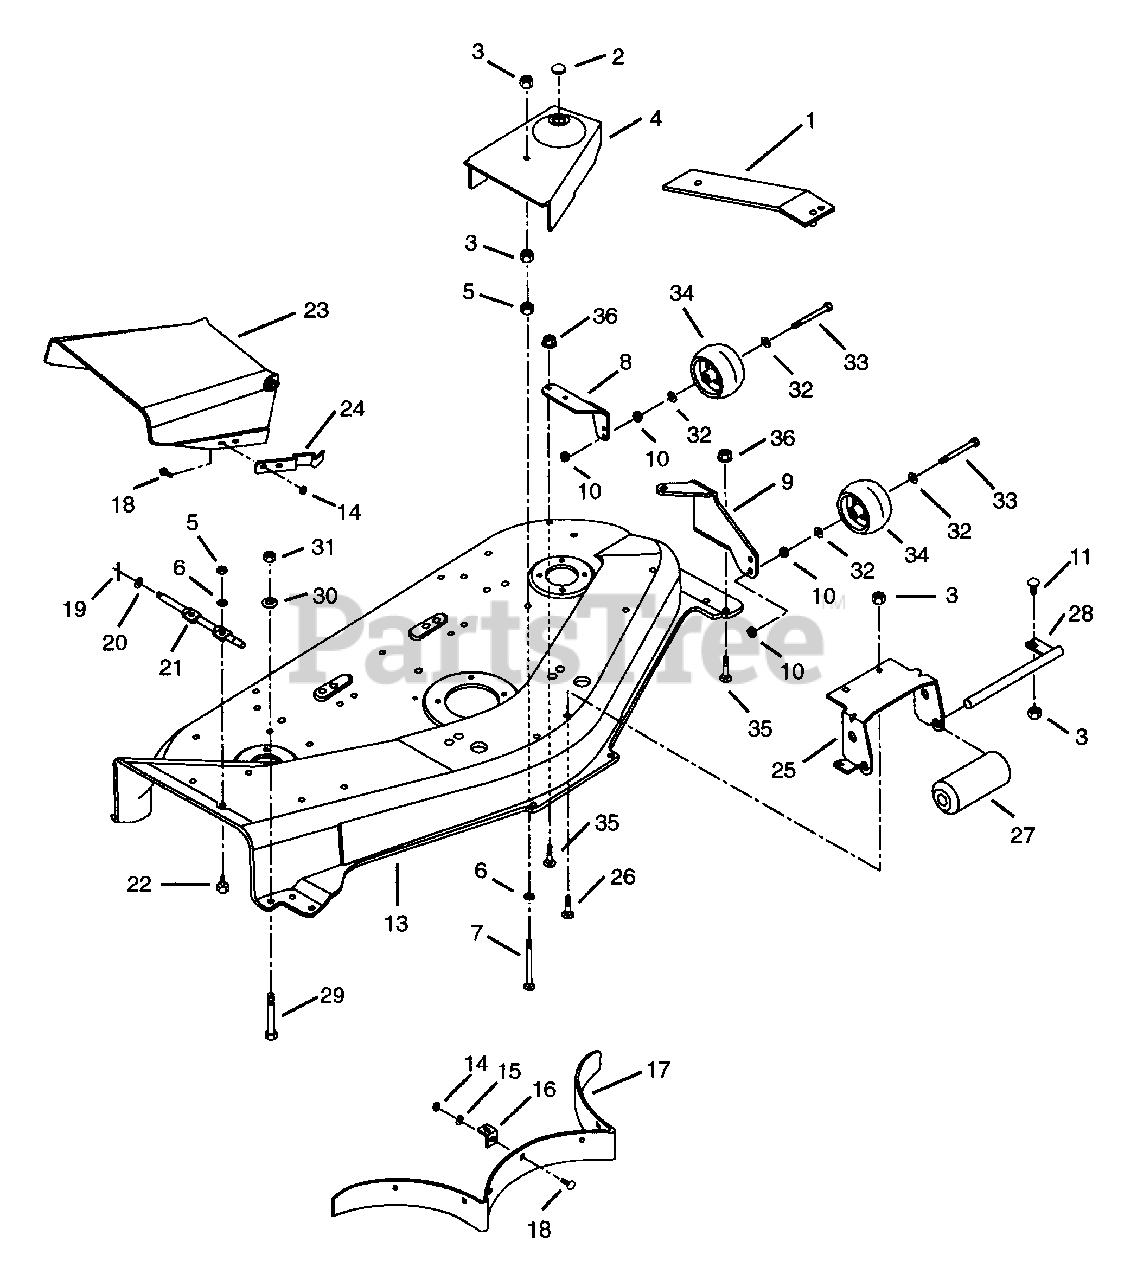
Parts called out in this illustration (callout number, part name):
2	BUTTON PLUG 1.0
3	NUT-LK .312-18 GR A PL
4	COVER, R.H. BELT
4	BELT COVER L H 48"
5	NUT-HEX .312-18
6	WSHR-LK .312X.097 PL HVY
7	BLT-RDHDSQNK .31-18X3.25 SHTPL
8	LH REAR BRACKET
9	LH FRONT BRACKET
10	NUT-LK-CTR .375-16 GR A PL
11	BLT-RDHDSQNK .31-18X.75 GR5 PL
12	BLT-RDHDSQNK .31-18X1.0 SHT PL
13	MOWER PAN W/DECALS 48"- ORANGE
14	NUT-LK-CTR .250-20 PL
15	WSHR-FL-STL.281X.62X.065 PL
16	BAFFLE TAB
18	BLT-RDHDSQNK .25-20X.50 SHT PL
19	PIN-COTR .09X.75 PL
20	WSHR-FL-STL.406X.812X.065PL
21	HINGE PIN
22	BLT-HEX .31-18X.75 PL GR5
23	CHUTE EXTENSION
24	SPRING, FLAT
25	BRACKET, ROLLER
26	BLT-RDHDSQNK .312-18X.62 PL
28	ROLLER SHAFT
29	BLT-HEX.38-16X2.5FTHD GR2 YWZC
30	WSHR-LK .375X.115 HVY PL
31	NUT-HEX .375-16
32	WSHR-FL-STL .38X.875X.083 PL
33	BLT-HEX .38-16X3.50 PL GR5
35	BLT-RDHDSQNK.31-18X.75GR5SHTPL
36	NUT-FLG. .312-18 PL
